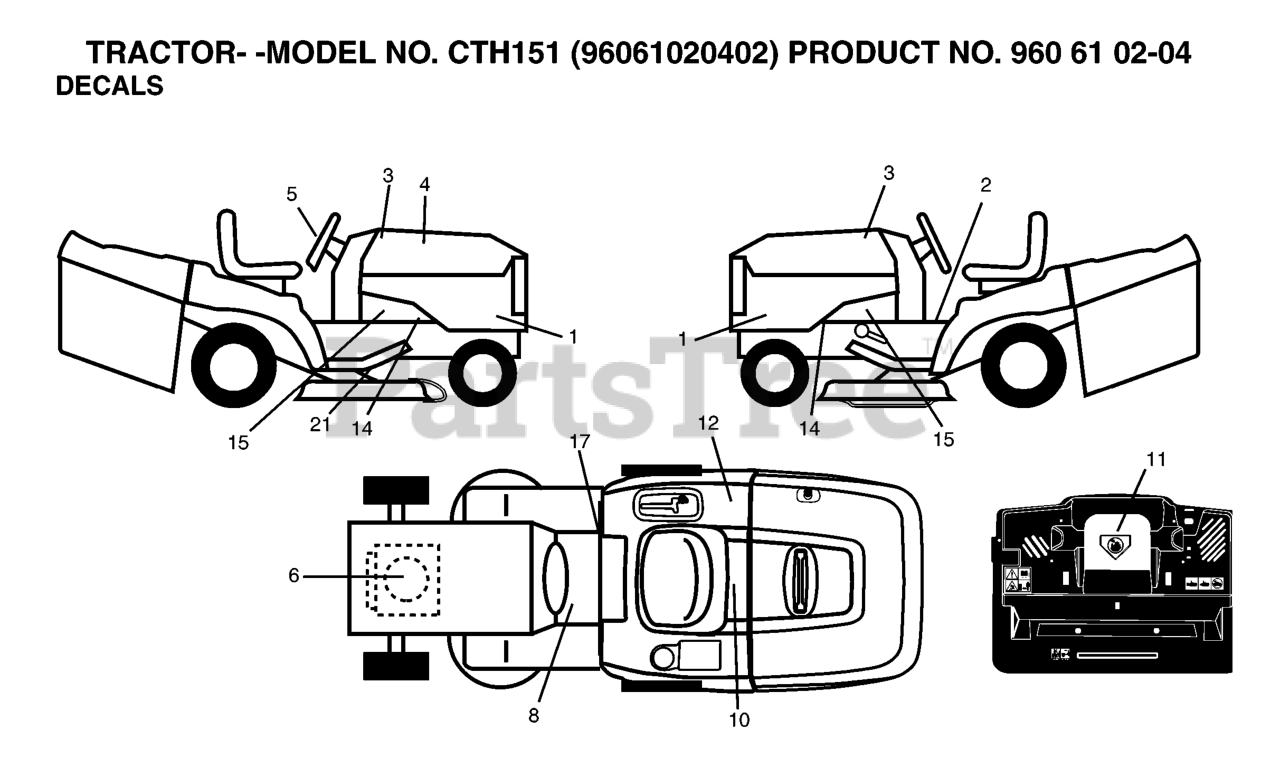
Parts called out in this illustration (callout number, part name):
1	DECAL PANEL
2	LABEL
3	DECAL.HOOD.NAMELOGO.HUSQ
5	DECAL.WHEEL.STRG.LGN.H
6	DECAL
8	DECAL
10	DECAL BTRY SYMBOLS
11	DECAL.INTERNATIONL.CUTFINGER
12	Decal, Fender 100 DB/CE
17	DECAL PARK BRAKE
